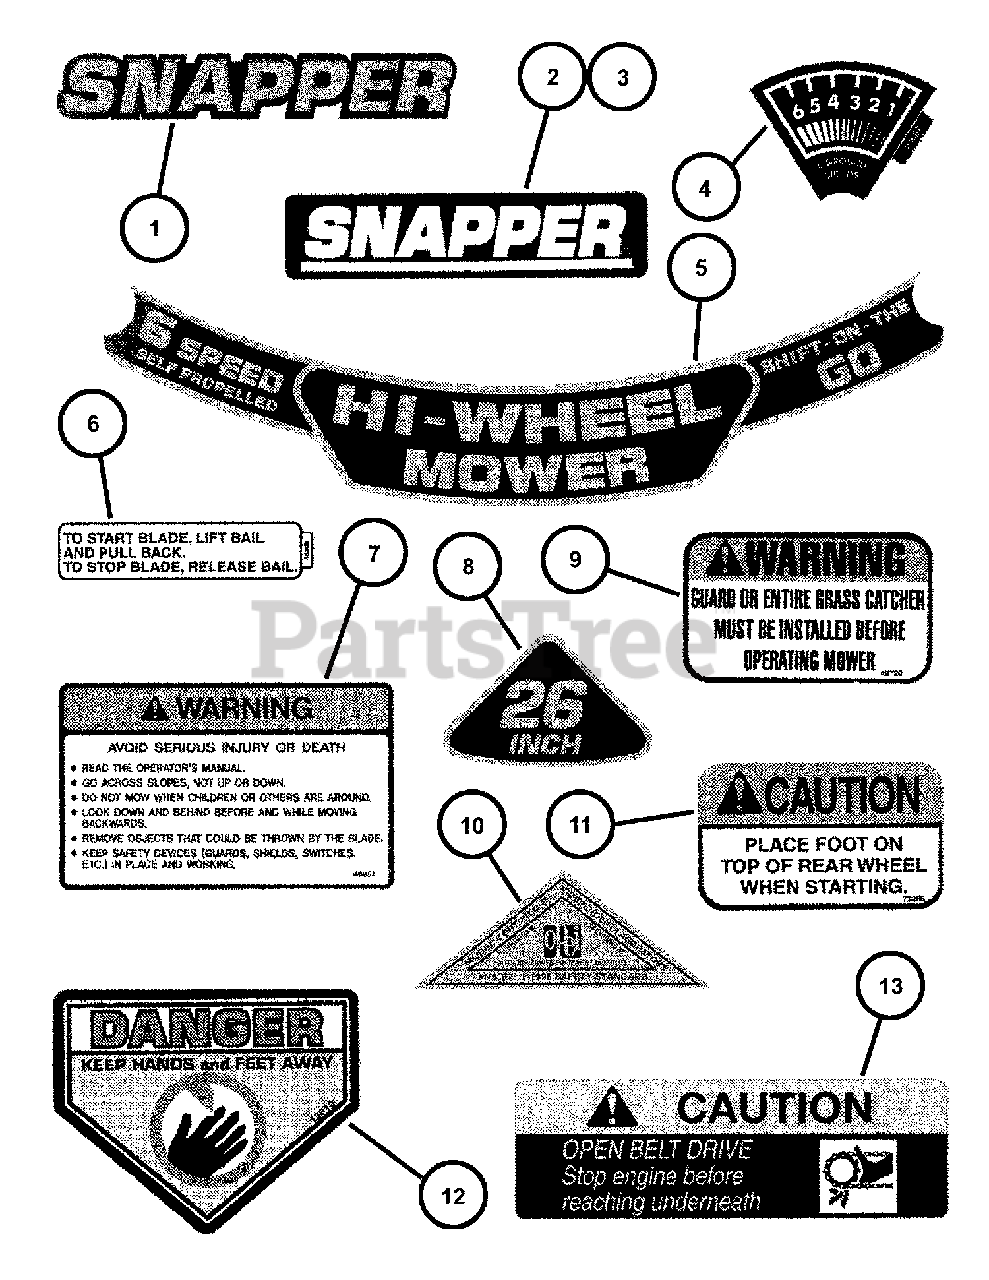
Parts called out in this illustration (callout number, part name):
1	DECAL, SNAPPER - 3D
2	DECAL, SNAPPER (White Letters)
3	DECAL, SNAPPER (Silver Letters)
4	DECAL, Speed Sector
5	DECAL, Hi-Wheel Mower
6	DECAL, Blade Brake Clutch Control
7	DECAL, Warning 1997
8	DECAL, 26"
9	DECAL, Discharge Chute 26" & 30"
10	DECAL, OPEI
11	DECAL, Stabilization
12	DECAL, Danger, Cut Finger
13	DECAL, Caution
